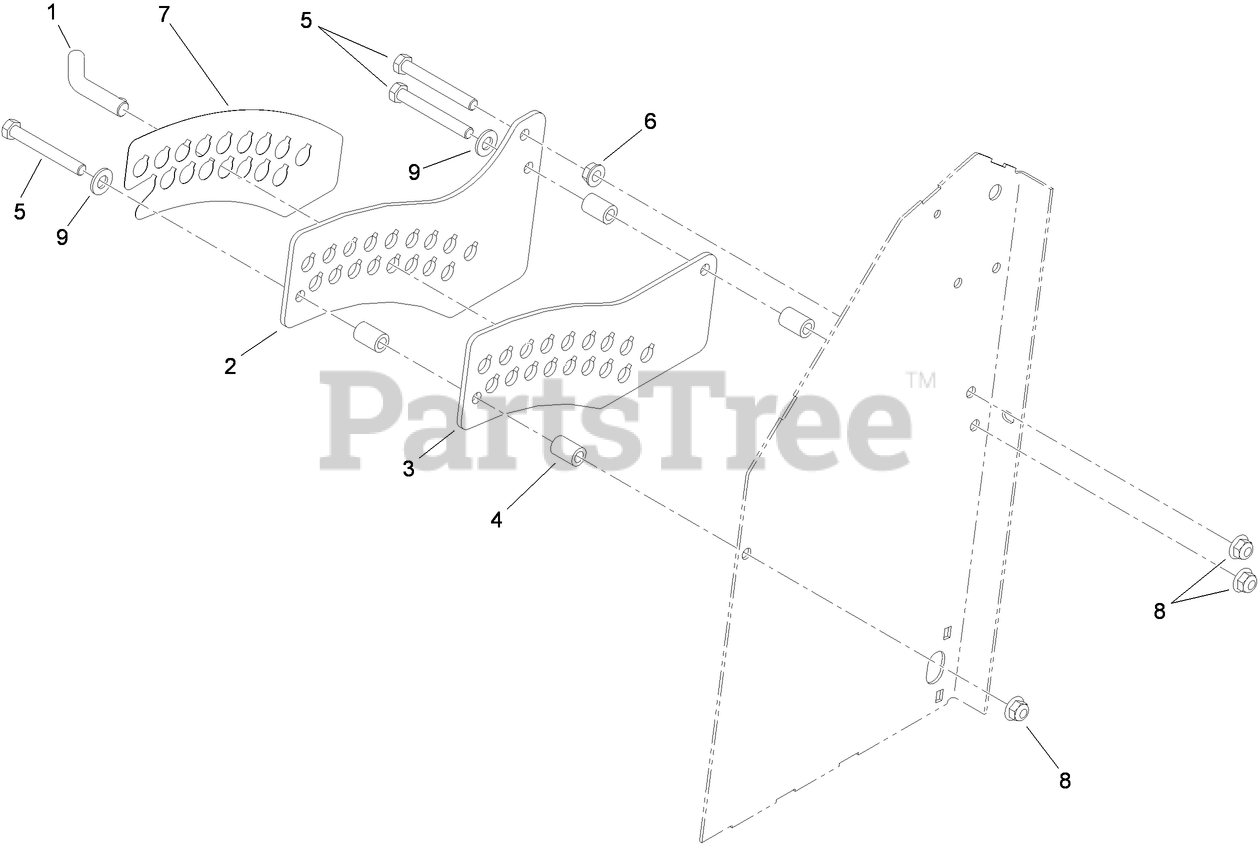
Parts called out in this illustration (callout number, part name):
1	PIN-HOC
2	PLATE-HOC, OUTSIDE
3	PLATE-HOC, INSIDE
4	SPACER
5	SCREW-HH
6	NUT-HHF, WHIZ
7	DECAL-HOC
8	NUT-HF, NI
9	WASHER-FLAT
